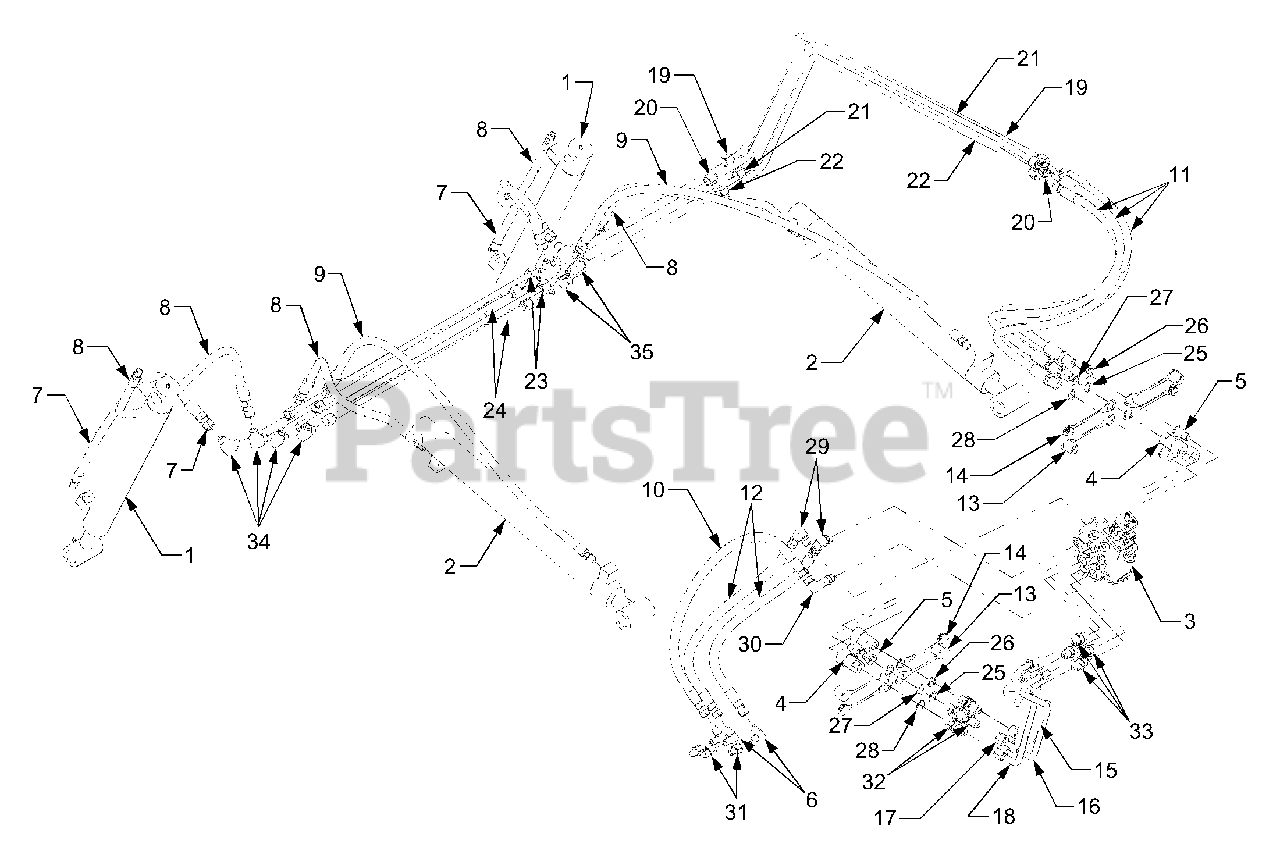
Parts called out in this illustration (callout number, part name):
1	Cylinder, Loader Bucket
2	Cylinder, Loader Boom
3	Valve, Loader Control
4	Coupling, Hydraulic - Female
5	Coupling, Hydraulic - Male
6	Fitting, Elbow Adapter
7	Hose, Hydraulic - Bucket Curl
8	Hose, Hydraulic - Boom Lift
9	Hose, Hydraulic - Boom Lower
10	Hose, Hydraulic - Inlet
11	Hose, Hydraulic - Loader
12	Hose, Hydraulic - Pressure
13	Plug, Hydraulic Coupler - Female
14	Plug, Hydraulic Coupler - Male
15	Tube, Bucket Curl
16	Tube, Bucket Dump
17	Tube, Boom Lift
18	Tube, Boom Lower
19	Tube, Hydraulic - Bucket Curl
20	Tube, Hydraulic - Bucket Dump
21	Tube, Hydraulic - Boom Lift
22	Tube, Hydraulic - Boom Lower
23	Tube, Hydraulic - Loader Front
24	Tube, Hydraulic - Loader Rear
25	Washer, Indicator - Blue
26	Washer, Indicator - Green
27	Washer, Indicator - Red
28	Washer, Indicator - Yellow
29	Fitting, 90 Degree
30	Fitting, 90 Degree - Long
31	Fitting, Adapter
32	Fitting, Bulkhead - Male
33	Fitting, Straight
34	Fitting, Union Elbow
35	Fitting, Union Tee
